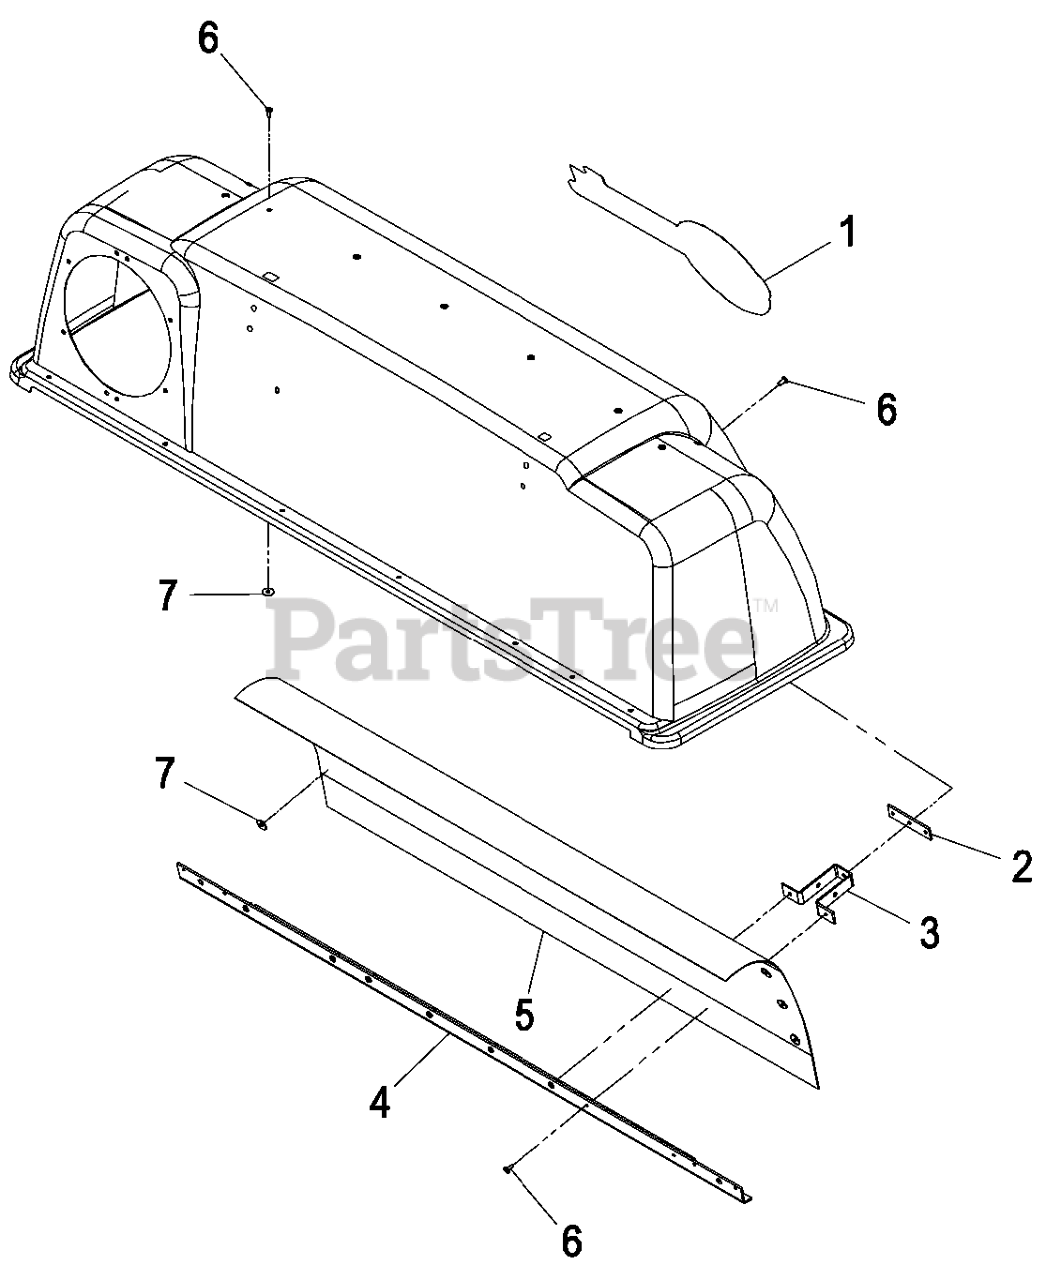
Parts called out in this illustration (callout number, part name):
1	DECAL, EXMARK
2	PLATE-LATCH, REINFORCEMEN
3	BRACKET-MOUNT
4	SUPPORT-SCREEN
5	SCREEN-BAGGER
6	RIVET-BLIND
